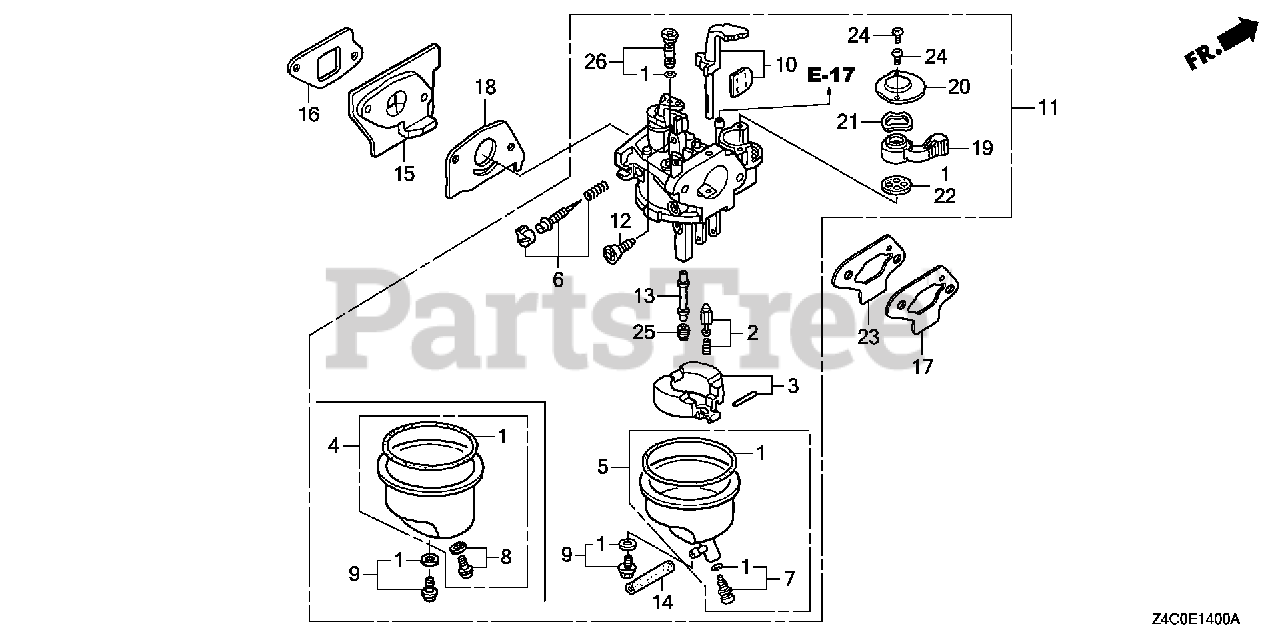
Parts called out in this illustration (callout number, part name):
1	GASKET SET
2	VALVE SET, FLOAT (CARBURETOR NO.) (SEAT NOT INCLUDED)
4	CHAMBER SET, FLOAT (CARBURETOR NO.)
6	SCREW SET (Honda Code 4219879). (CARBURETOR NO.)
6	SCREW SET
8	SCREW SET, DRAIN (Honda Code 1672187). (CARBURETOR NO.)
9	SCREW SET (CARBURETOR NO.)
10	CHOKE SET (CARBURETOR NO.)
11	CARBURETOR ASSY. (BF32E G)
11	CARBURETOR ASSY. (BF32K A)
12	SCREW, THROTTLE STOP
13	NOZZLE, MAIN (CARBURETOR NO.)
15	INSULATOR, CARBURETOR
16	GASKET, INSULATOR (ENGINE NO.)
18	GASKET, CARBURETOR
19	LEVER, VALVE (CARBURETOR NO.)
20	PLATE, LEVER SETTING (CARBURETOR NO.)
21	SPRING, PETCOCK LEVER (CARBURETOR NO.)
22	GASKET, VALVE
24	SCREW, PAN (3X6)
25	JET, MAIN (#48) (CARBURETOR NO.)
25	JET, MAIN (#50) Use from Engine SN BF12A B.
25	JET, MAIN (#52) Use from Engine SN BF12A B.
26	JET SET, PILOT (#35)
